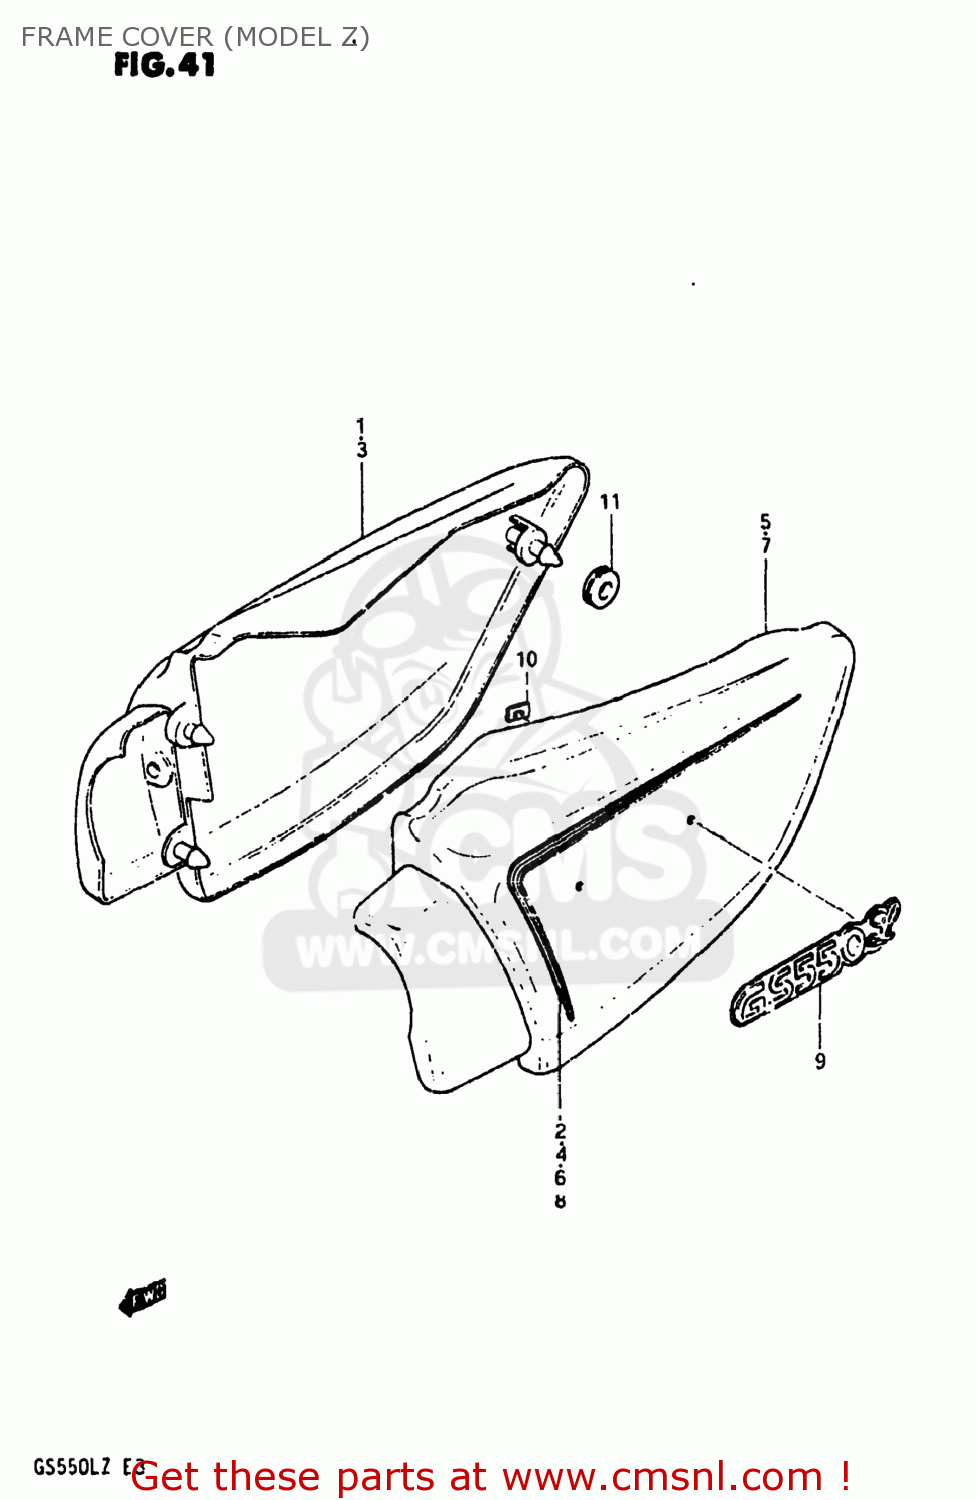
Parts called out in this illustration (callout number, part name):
1	COVER,FRAME,RIGHT
2	TAPE,FRAME COVER
3	COVER,FRAME,RIGHT
4	TAPE,FRAME COVER
5	COVER ASSEMBLY,FRAME,LEFT
6	TAPE,FRAME COVER
7	COVER ASSEMBLY,FRAME,LEFT
8	TAPE,FRAME COVER
9	EMBLEM,FRAME COVER
10	NUT
11	CUSHION
